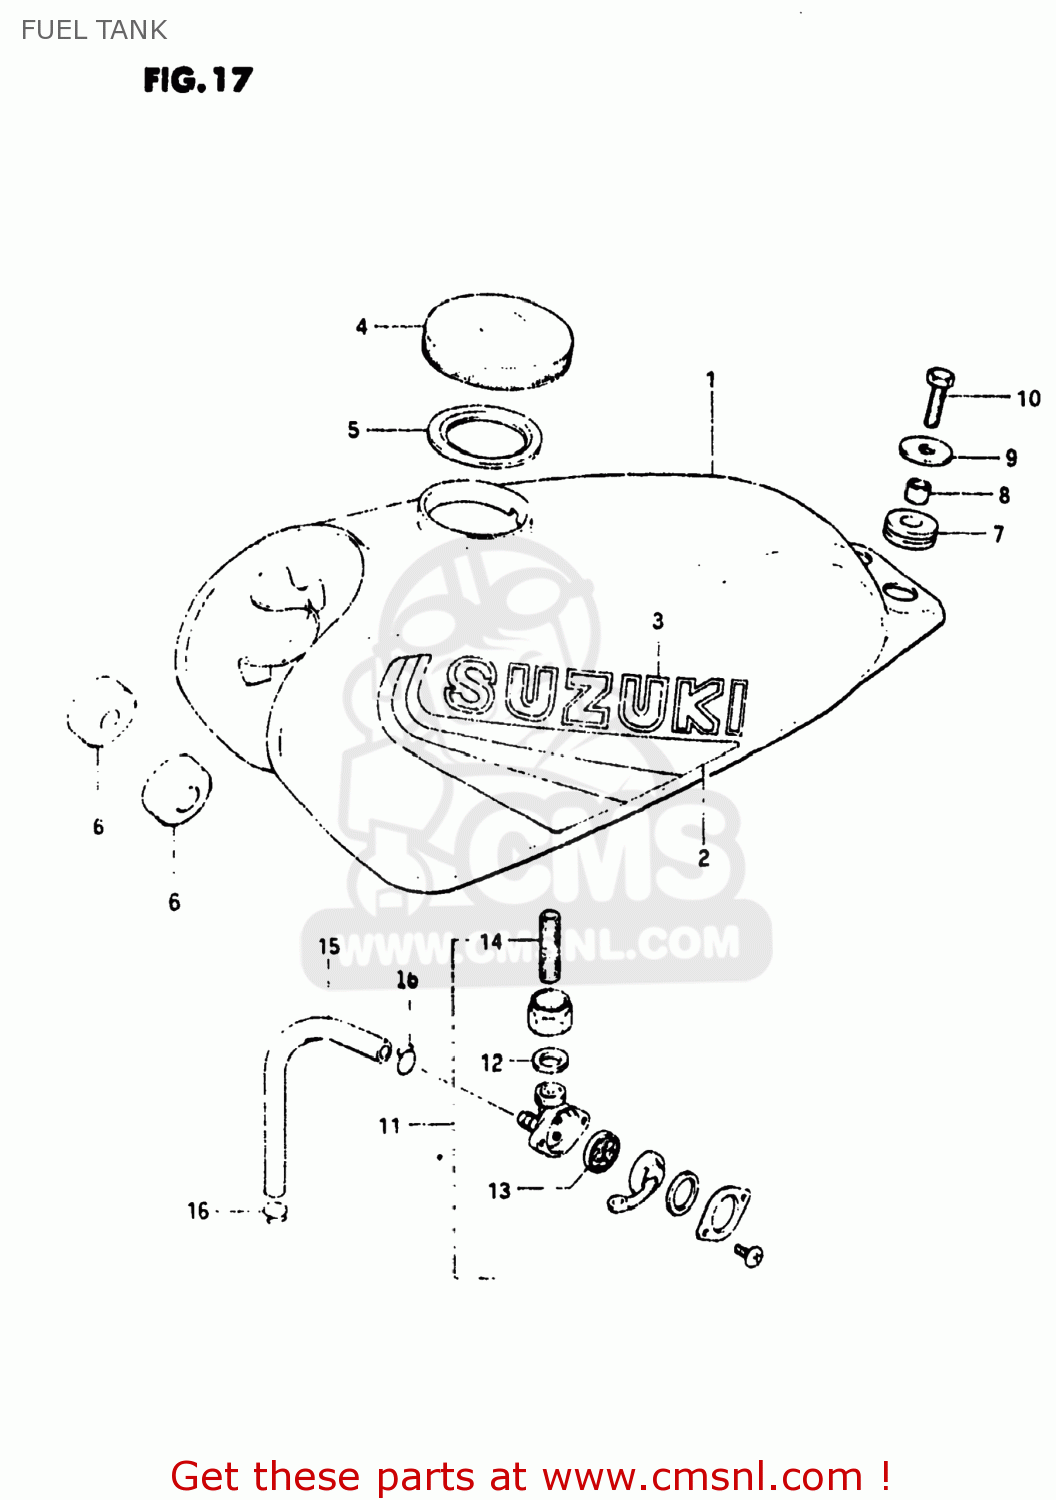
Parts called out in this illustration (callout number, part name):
1	TANK ASSEMBLY,FUEL
2	TAPE SET,FUEL TANK
3	EMBLEM(BLACK)
4	CAP SET,FUEL TANK
5	GASKET,CAP (NAS)
6	CUSHION
7	CUSHION
8	SPACER(6.1X9X7.5)
9	WASHER (6.5X24X1.6)
10	BOLT, UPPER
11	COCK ASSEMBLY,FUEL
12	GASKET,FUEL COCK (NAS)
13	PACKING,VALVE (NAS)
14	FILTER,FUEL
15	HOSE
16	CLIP
